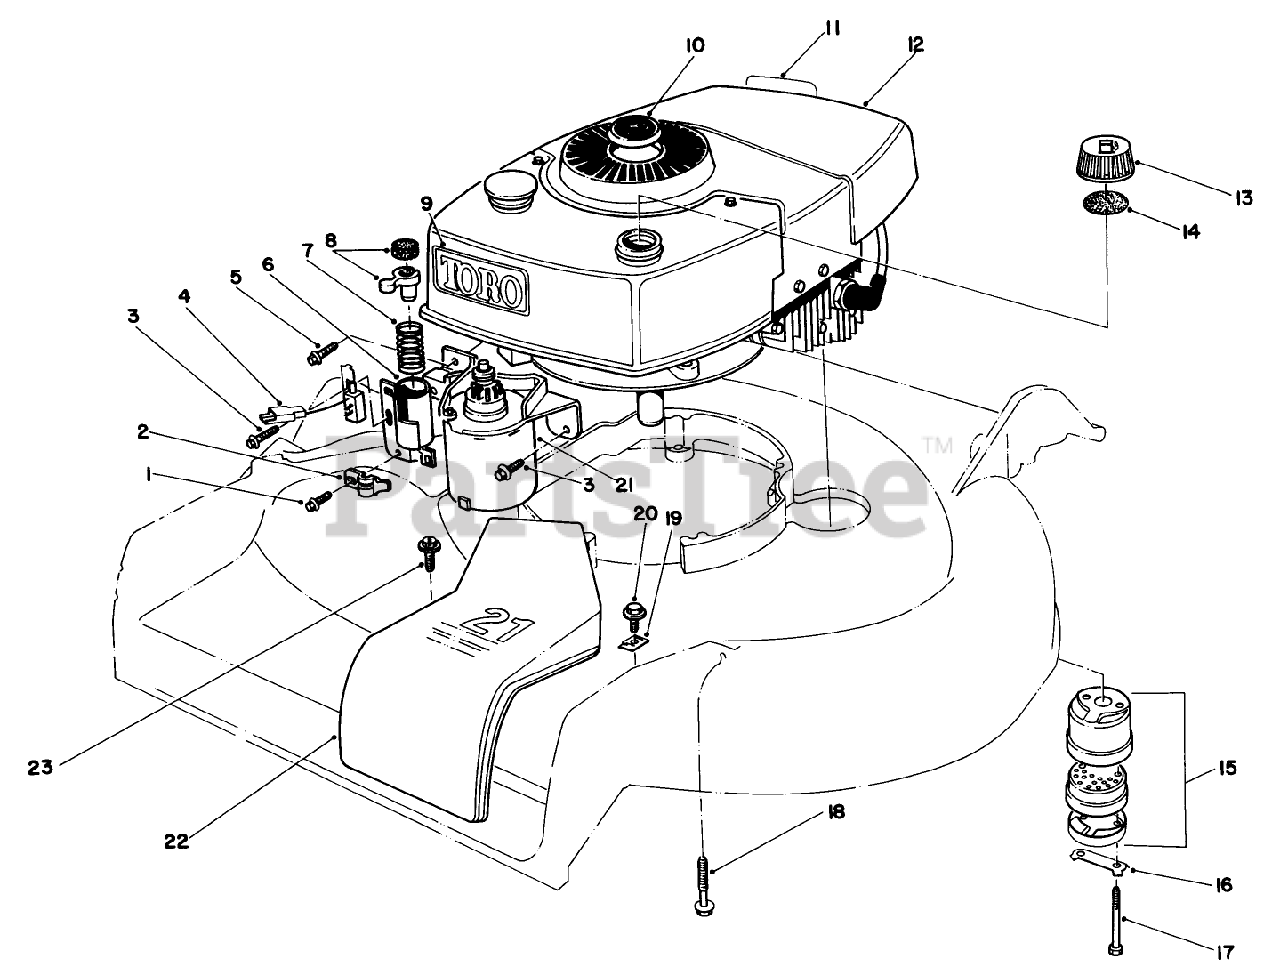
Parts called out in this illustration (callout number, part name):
1	SCREW
3	SCREW
10	PLUG BUTTON
12	Engine
14	GAS CAP GASKET
15	MUFFLER ASM
16	CLIP - LOCKING
17	SCREW-HH
18	3/8-16 X 2-3/4 CAPSCR
20	SCREW-HWHTF
22	BELT COVER 21" S D
23	SCREW
